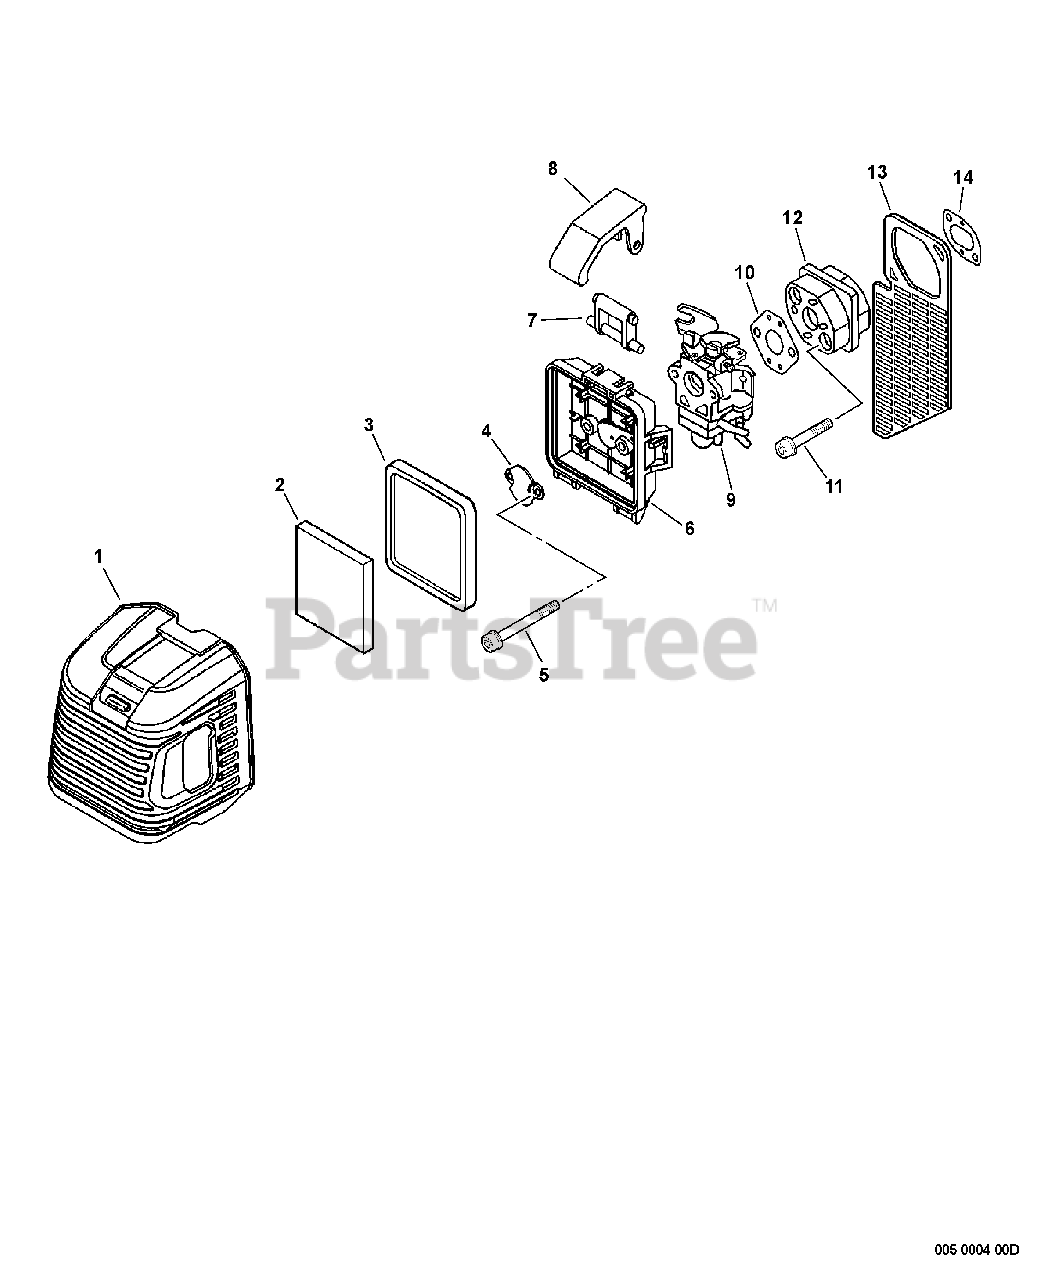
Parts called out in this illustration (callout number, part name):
1	COVER, AIR FILTER
2	FILTER, AIR
3	FILTER, AIR
4	PLATE, PREVENT
5	SCREW - 5X55
6	CASE, AIR FILTER
8	LATCH, CLEANER LID
9	CARBURETOR
10	GASKET, INTAKE
11	SCREW - 5X25
12	INSULATOR, INTAKE
13	GUARD, DEBRIS
14	GASKET, INTAKE
